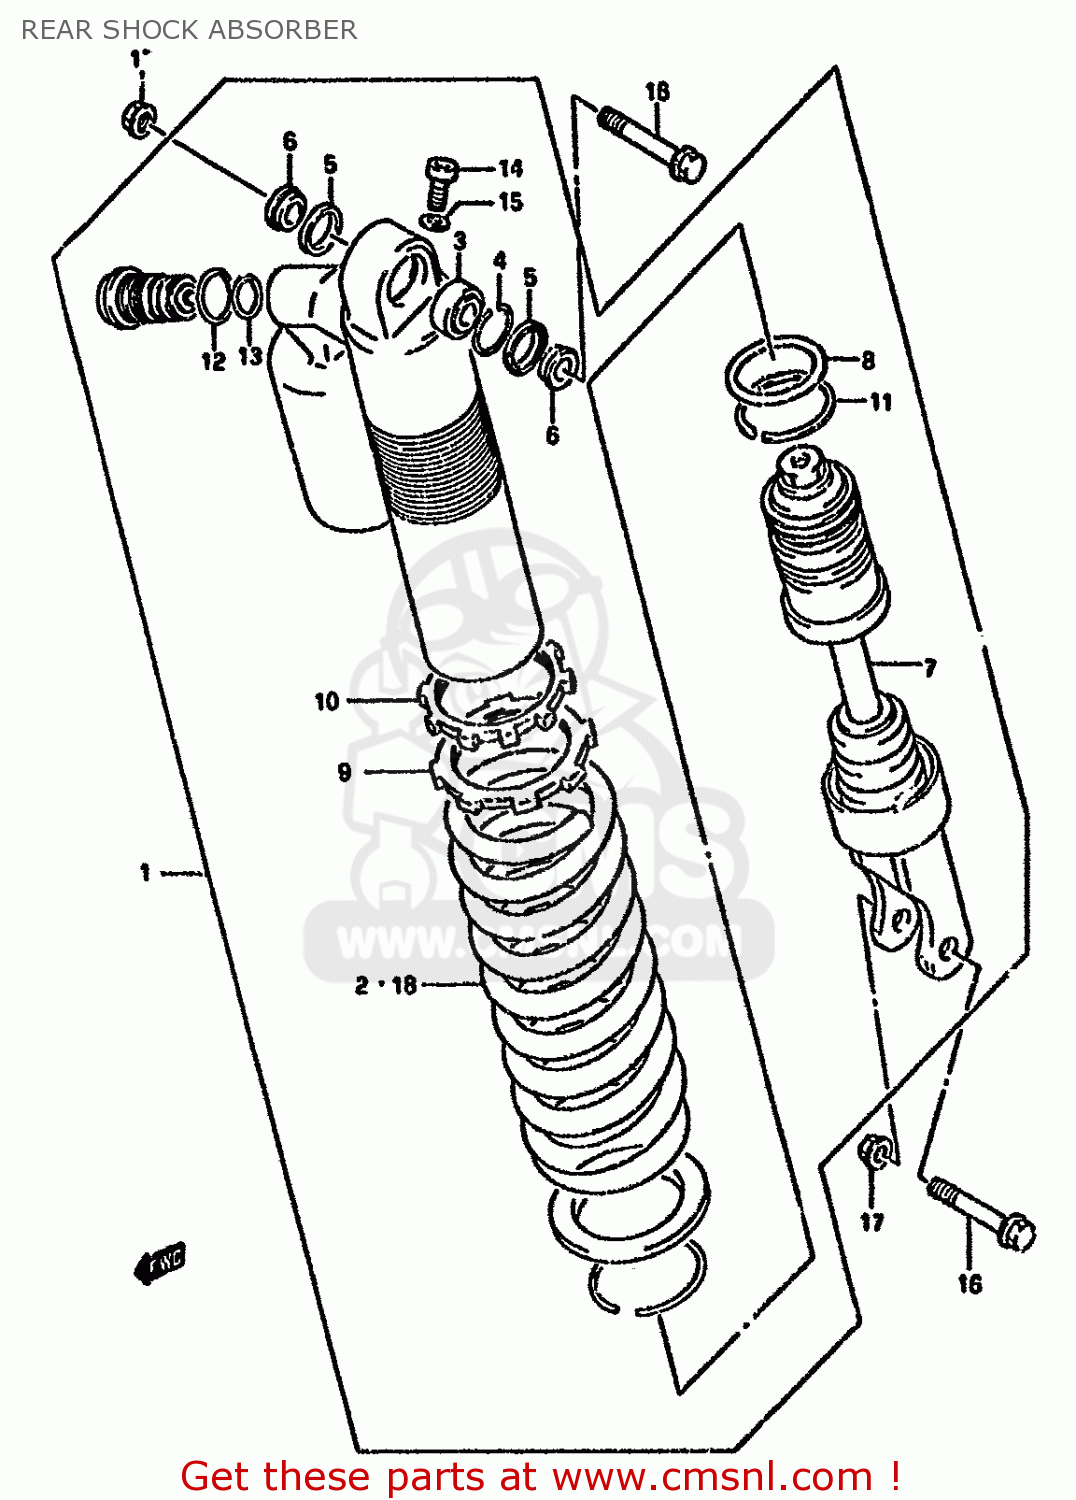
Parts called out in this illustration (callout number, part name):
1	ABSORBER ASSEMBLY,REAR SHOCK
2	SPRING
3	BEARING,RR CUSHION LEVER RR
4	RING,STOPPER
5	SEAL,DUST
6	COLLAR
7	ROD,PISTON
8	O RING
9	GUIDE,SPRING
10	NUT
11	RING,STOPPER
12	O RING
13	O RING
14	BOLT
15	GASKET,DRAIN,PLUG (NAS)
16	BOLT,REAR SHOCK ABSORBER
17	NUT
18	SPRING,REAR (K=5.0)
